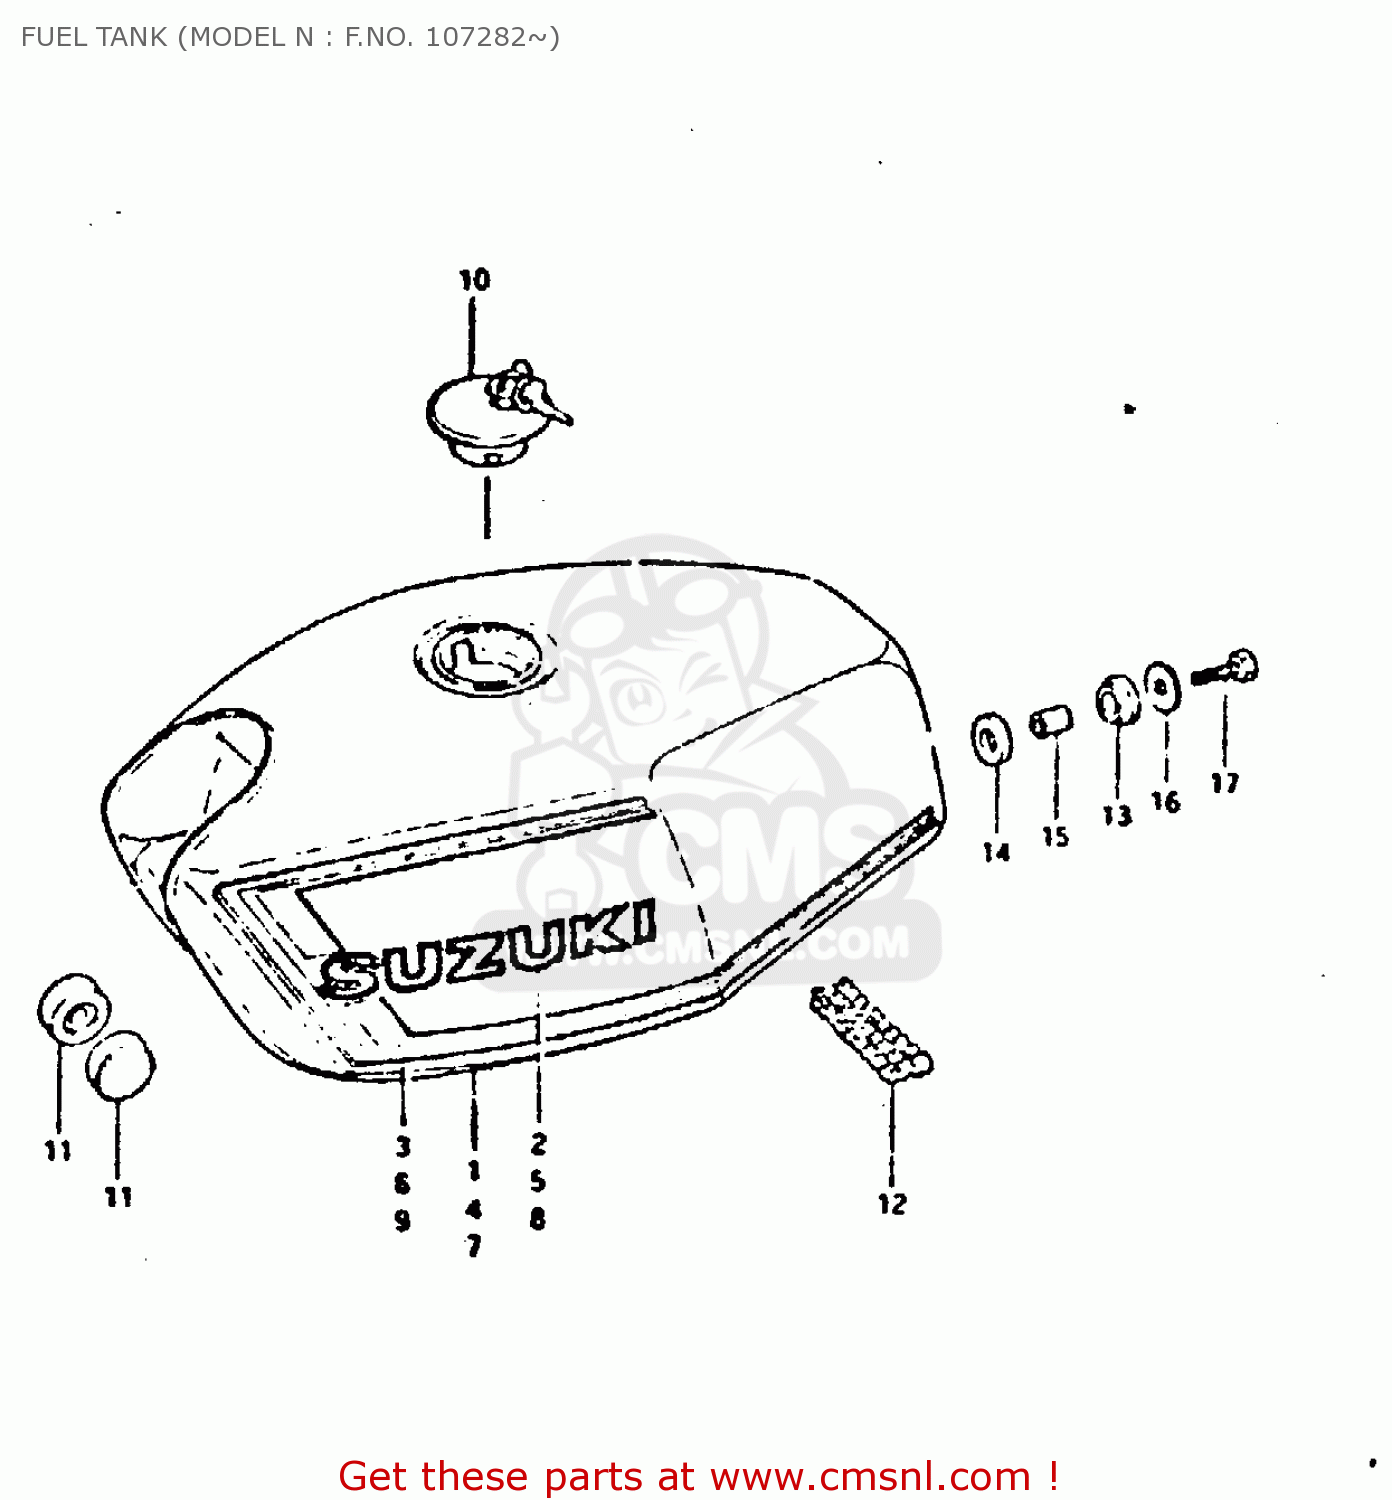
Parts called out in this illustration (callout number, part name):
1	TANK, FUEL (WHITE)
2	EMBLEM
3	TAPE SET
4	TANK, FUEL (RED)
5	EMBLEM
6	TAPE SET
7	TANK, FUEL (BLUE)
8	EMBLEM
9	TAPE SET
10	CAP SET,FUEL TANK
11	CUSHION
12	CUSHION
13	CUSHION
14	CUSHION
15	SPACER(8.5X12X19)
16	WASHER (8.5X29X1.6)
17	BOLT (8X30)
